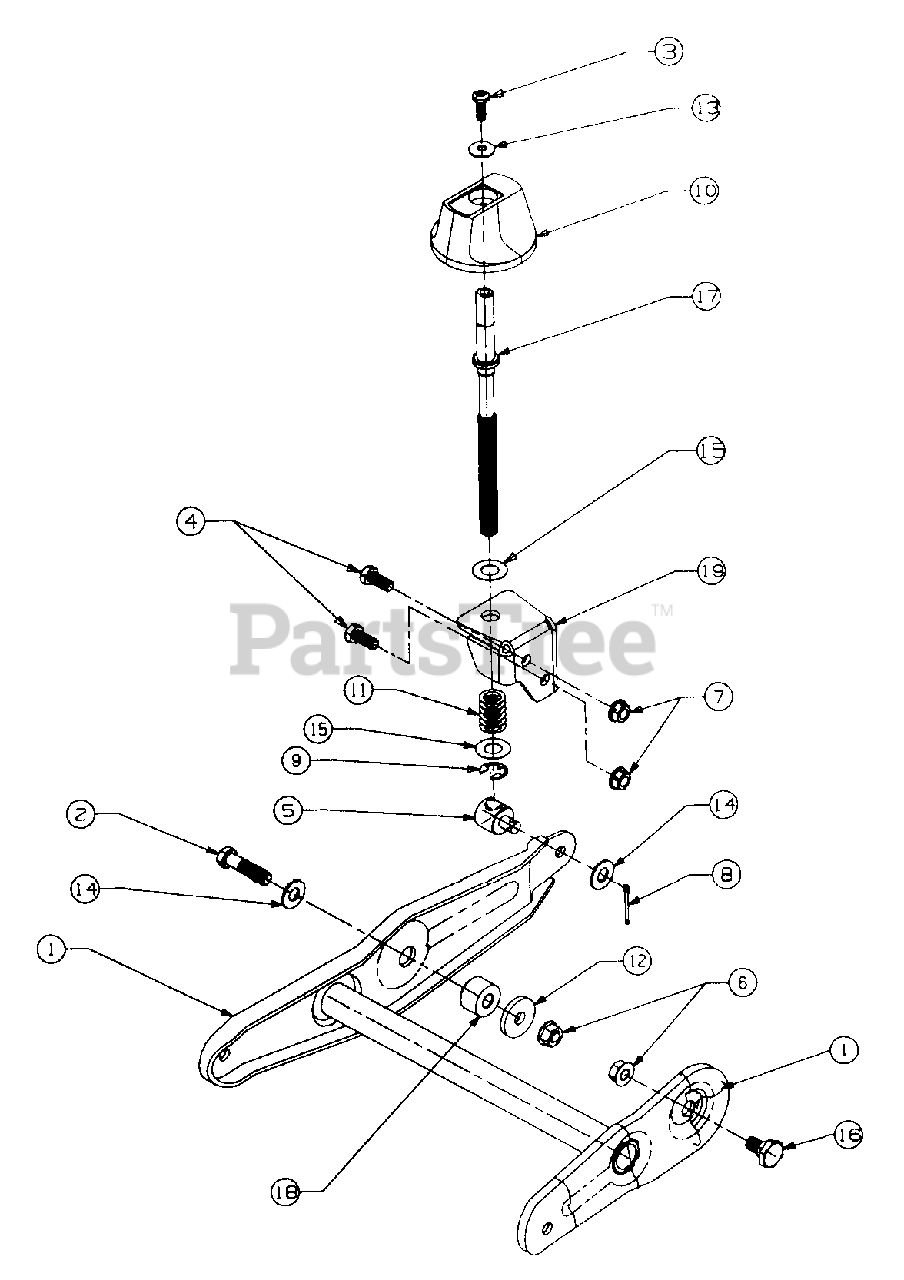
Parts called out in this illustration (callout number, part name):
3	SCREW - MACHINE PAN HD
5	FERRULE - ADJUSTABLE
6	NUT - HEX FLANGE LOCK
7	NUT - HEX FLANGE
8	PIN - COTTER
9	RING-E
10	KNOB - PLASTIC
11	SPRING - COMPRESSION
12	WASHER - FLAT
13	WASHER - BELL
14	WASHER - FLAT
15	WASHER - FLAT
16	SCREW - SHOULDER
17	ROD - ADJUSTABLE
